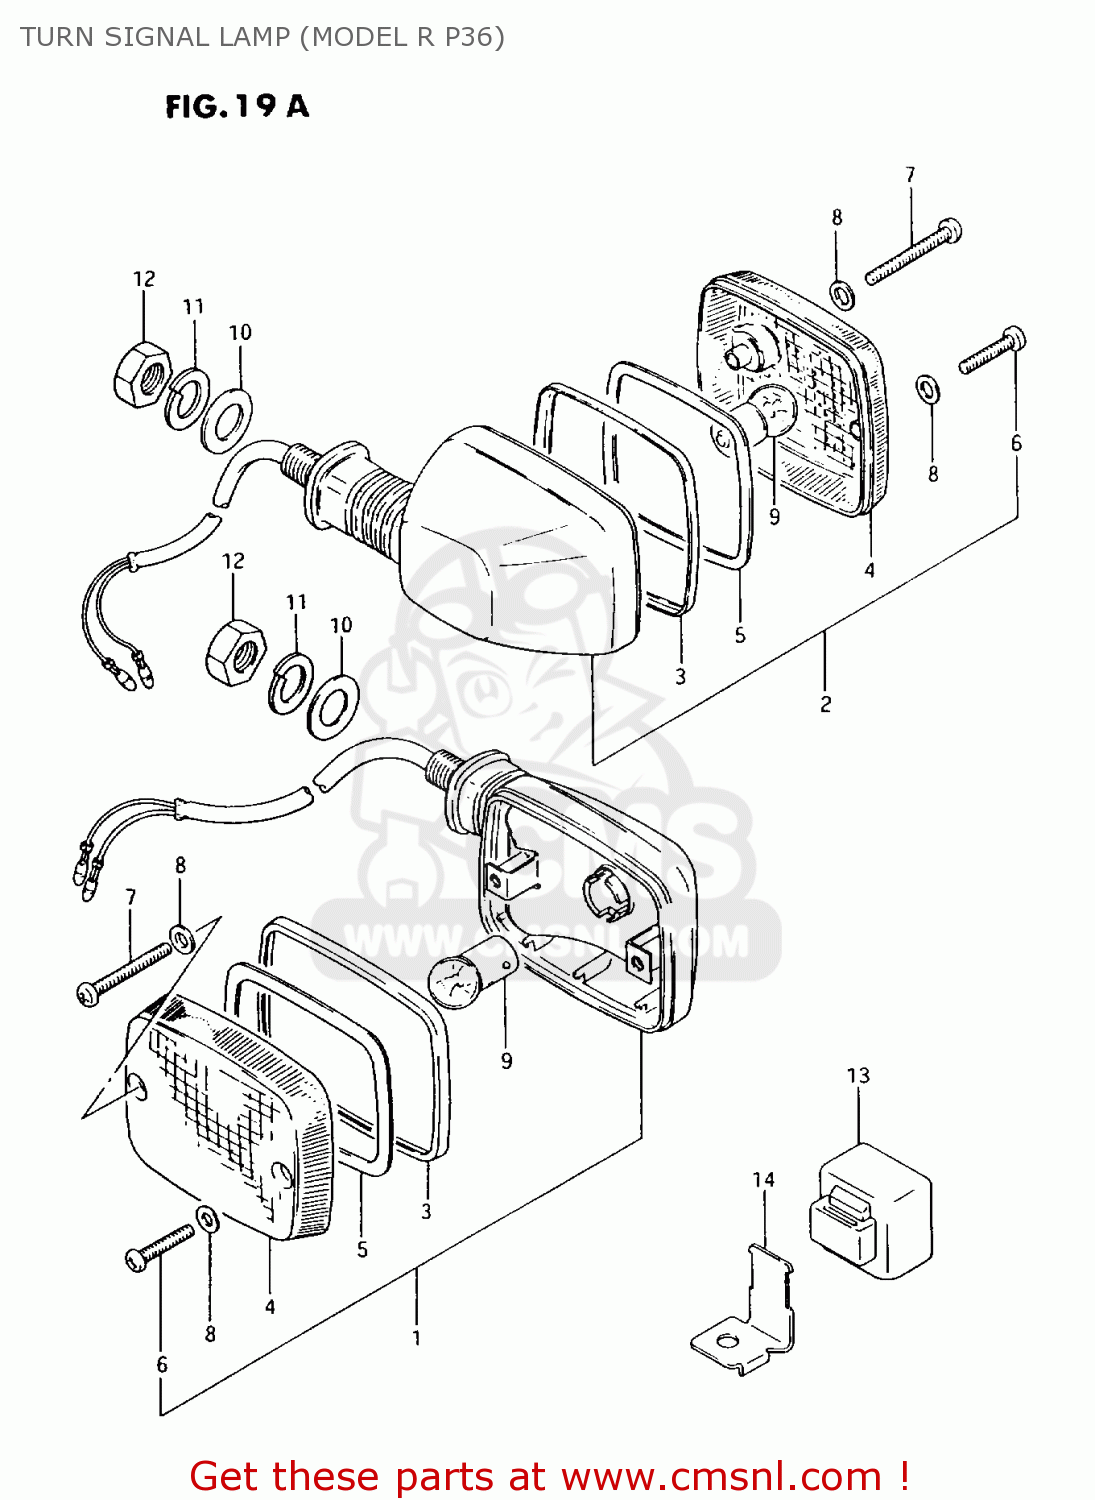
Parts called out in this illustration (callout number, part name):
1	LAMP ASSY,TURNSIGNAL
2	LAMP ASSY,RR TURNSIGNAL
3	RIM
4	LENS
5	GASKET (NAS)
6	SCREW
7	SCREW
8	GASKET (NAS)
9	BULB(6V8W,STANLEY,A4115)
10	WASHER
11	LOCK WASHER
12	NUT
13	RELAY,TURN SIGNAL
14	BRACKET,TURN SIGNAL RELAY
